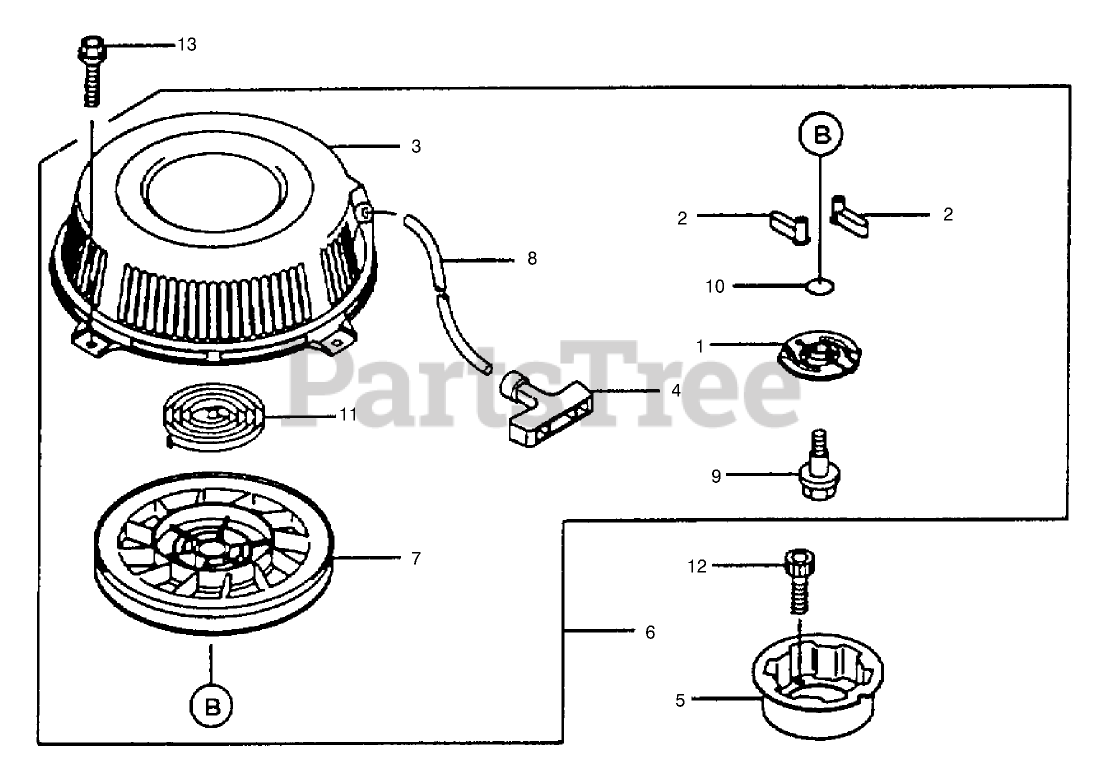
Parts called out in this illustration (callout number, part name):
1	Guide
2	Pawl-Recoil Starter
3	Case-Spring
4	Grip-Recoil Starter
5	Pulley-Starting
6	Starter-Recoil
7	Reel-Recoil Starter
8	Rope
9	Screw
10	Ring-Snap
11	Spring
12	Bolt-Socket
13	BOLT-FLANGED (6X10)
16	Starter-Recoil
